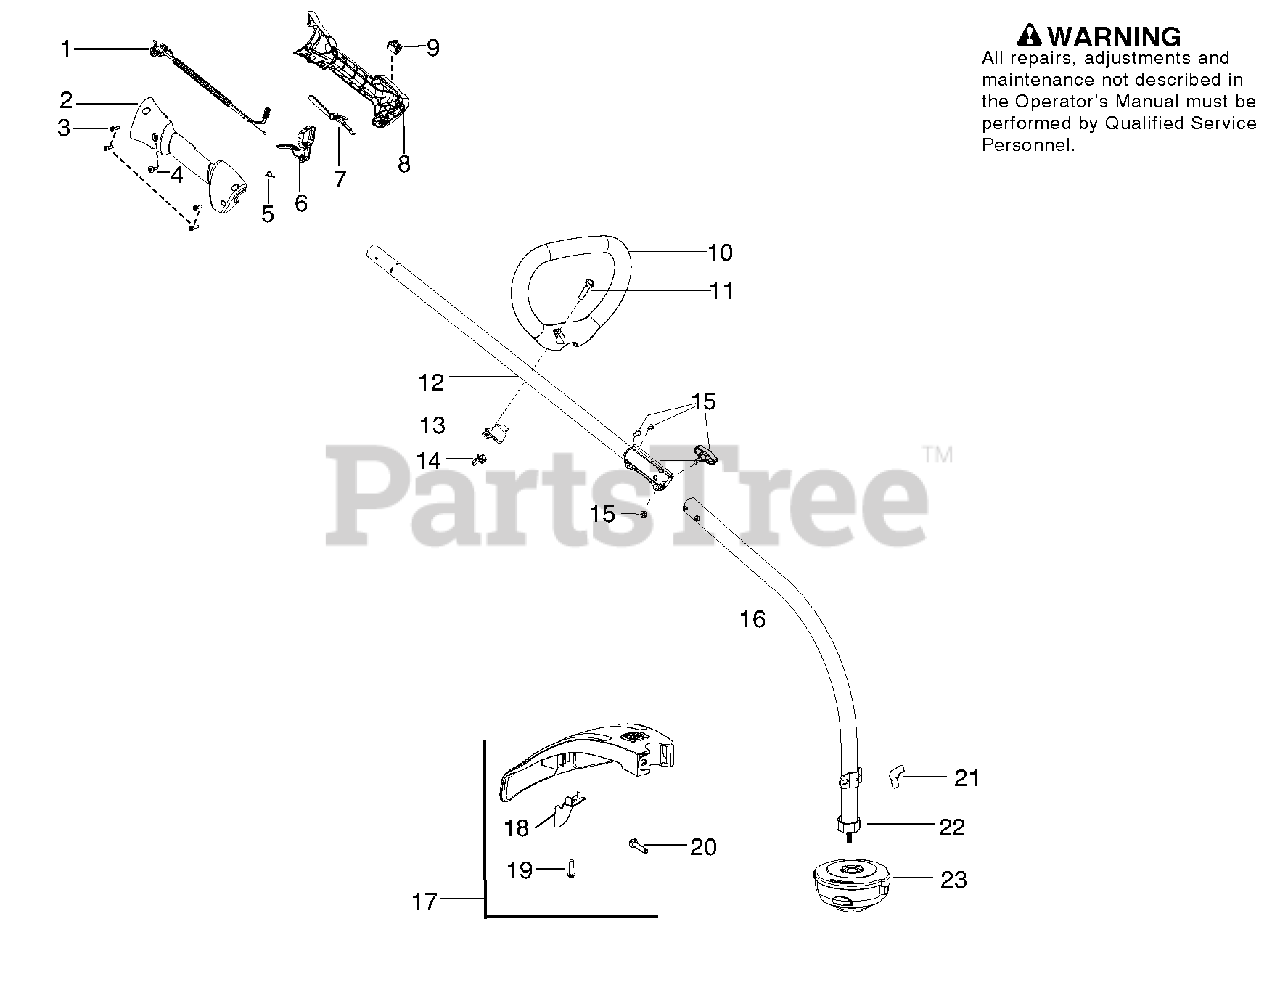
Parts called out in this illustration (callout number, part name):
1	Assy-Cable/Wire Harness
2	Housing-Throttle (RH)
3	Screw
4	Screw
5	Spring-Trigger
6	Trigger
7	Lockout-Throttle
8	Housing-Throttle (LH)
9	Kit-Switch
10	Handle - Assist
12	Kit-Driveshaft Upper
13	Clamp - Assist Handle
14	Wingnut
15	Kit - Knob / Screw
16	Kit-Lower Shaft
17	Kit-Shield
18	Limiter - Line
21	Wingnut
22	Dust Cup
23	Head - Cutting
